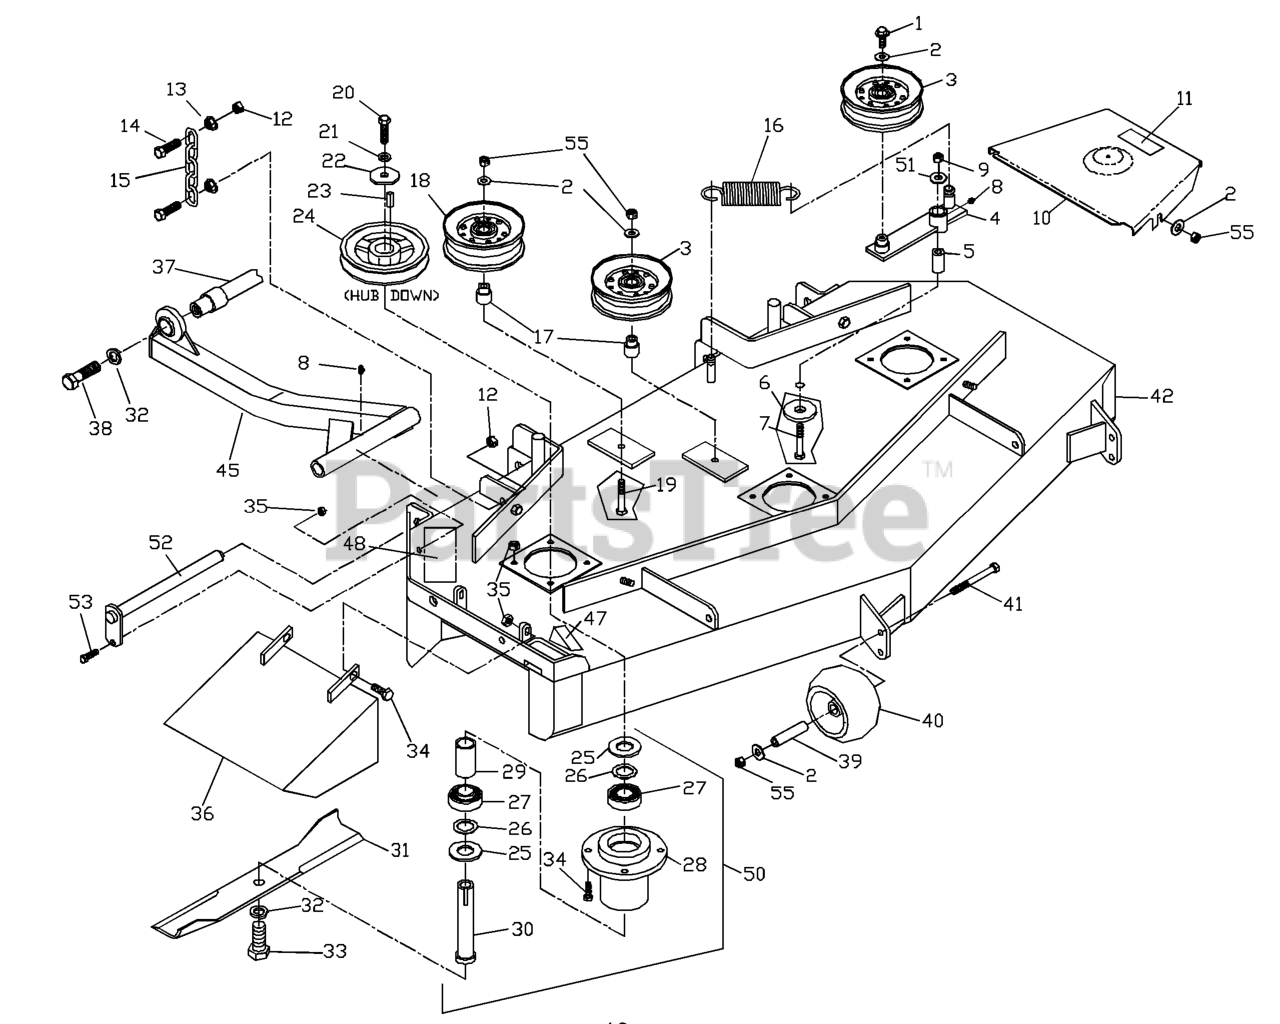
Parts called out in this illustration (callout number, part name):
1	4CS 3/8C X 1 SERRATED HEAD
2	WASHER 3/8 FLAT
3	IDLER PULLEY
5	PIVOT BUSHING
6	WASHER, SUPPORT
7	HCS 1/2C X 3 1/4
8	ZERK
9	NUT 1/2-13 HEX NYLOC ZD
10	BELTSHIELD
11	DECAL, NO STEP
12	NUT 7/16C CENTERLOCK
13	NUT 7/16C WHIZ
14	HCS 7/16C X 1 1/2
15	LIFT CHAIN
17	IDLER BUSHING
18	IDLER PULLEY (TALL)
19	HCS 3/8C X 2 1/2
20	HCS 7/16F X 1 1/2
21	WASHER 7/16 LOCK
22	WASHER, CRANKSHAFT
23	KEY 1/4 SQ X 1 1/8
25	MACHINERY BUSHING 10 GA.
26	BUSHING.MACHINE.18.GAUGE
27	BEARING
30	SPINDLE SHAFT
31	BLADE OEM 16 1/4"
32	LOCKWASHER 5/8
33	HCS 5/8F X 1 1/4
34	HCS 5/16C X 1
35	NUT 5/16C CENTERLOCK
36	DEFLECTOR CHUTE
37	STRUT MOUNT WELDMENT
38	HCS 5/8C X 2 GR.5
39	BUSHING
40	ANTI-SCALP ROLLER
41	HCS 3/8C X 3 1/2
42	DECK W/DECALS
45	STRUT WLDMT - RT
47	DECAL, CPSC
48	DECAL, DANGER
50	HOUSING, COMPLETE
51	WASHER 1/2 FLAT
53	HCS 5/16C X 3/4
55	NUT 3/8C CENTERBLOCK
